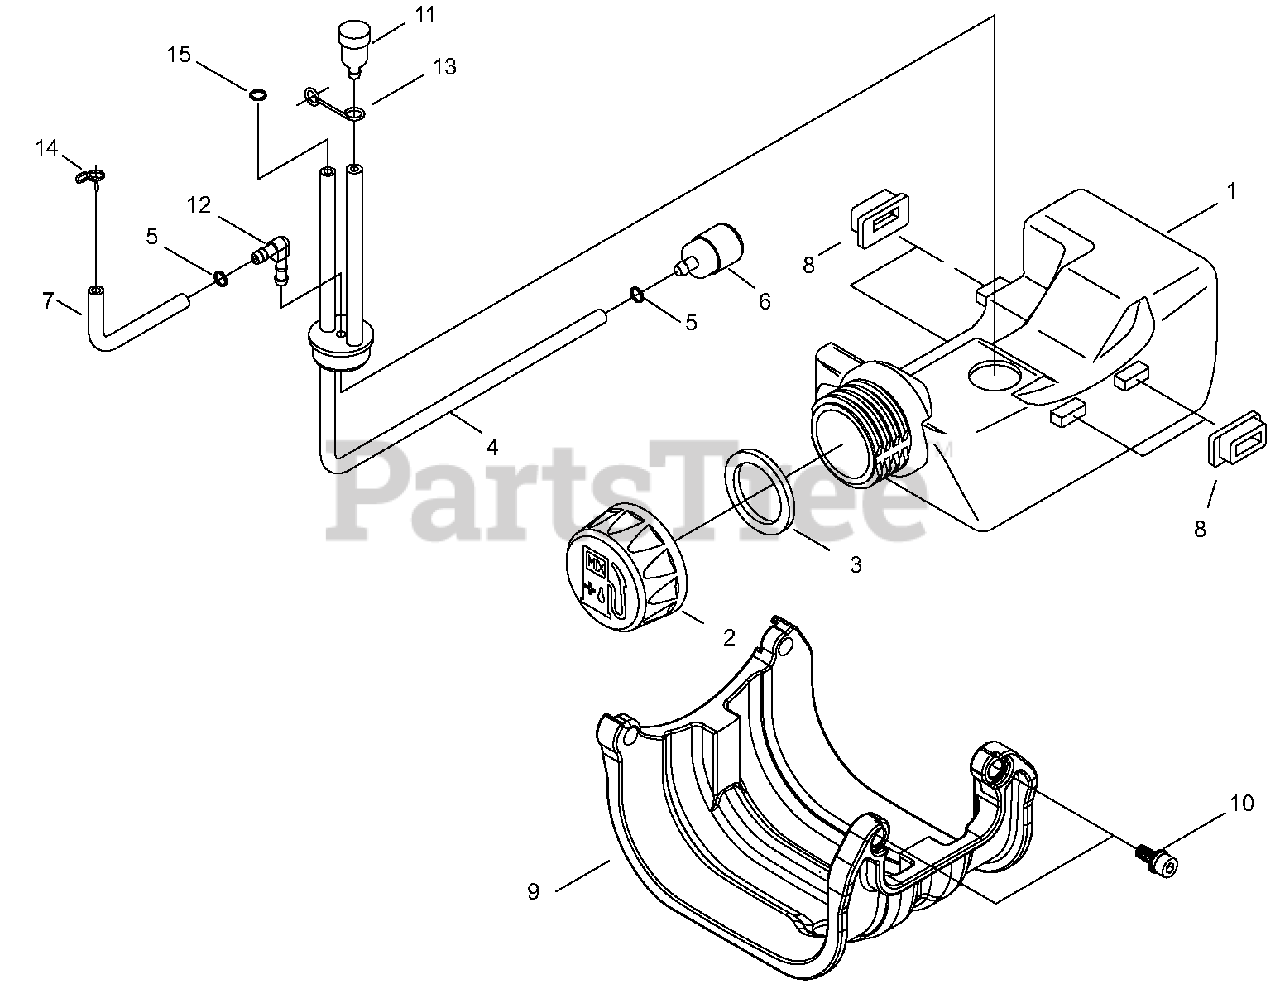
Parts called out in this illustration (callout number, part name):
1	TANK, FUEL
2	CAP, FUEL
3	GASKET, CAP
4	PIPE - FUEL
5	CLIP - 6
6	FILTER, FUEL
7	PIPE - RETURN
8	CUSHION, FUEL TANK
9	GUARD, FUEL TANK
10	SCREW - 5X16
11	VENT, FUEL TANK
12	CONNECTOR, PIPE
13	HOLDER, VENT
14	CLIP - BUTTERFLY
15	CLIP - 6
